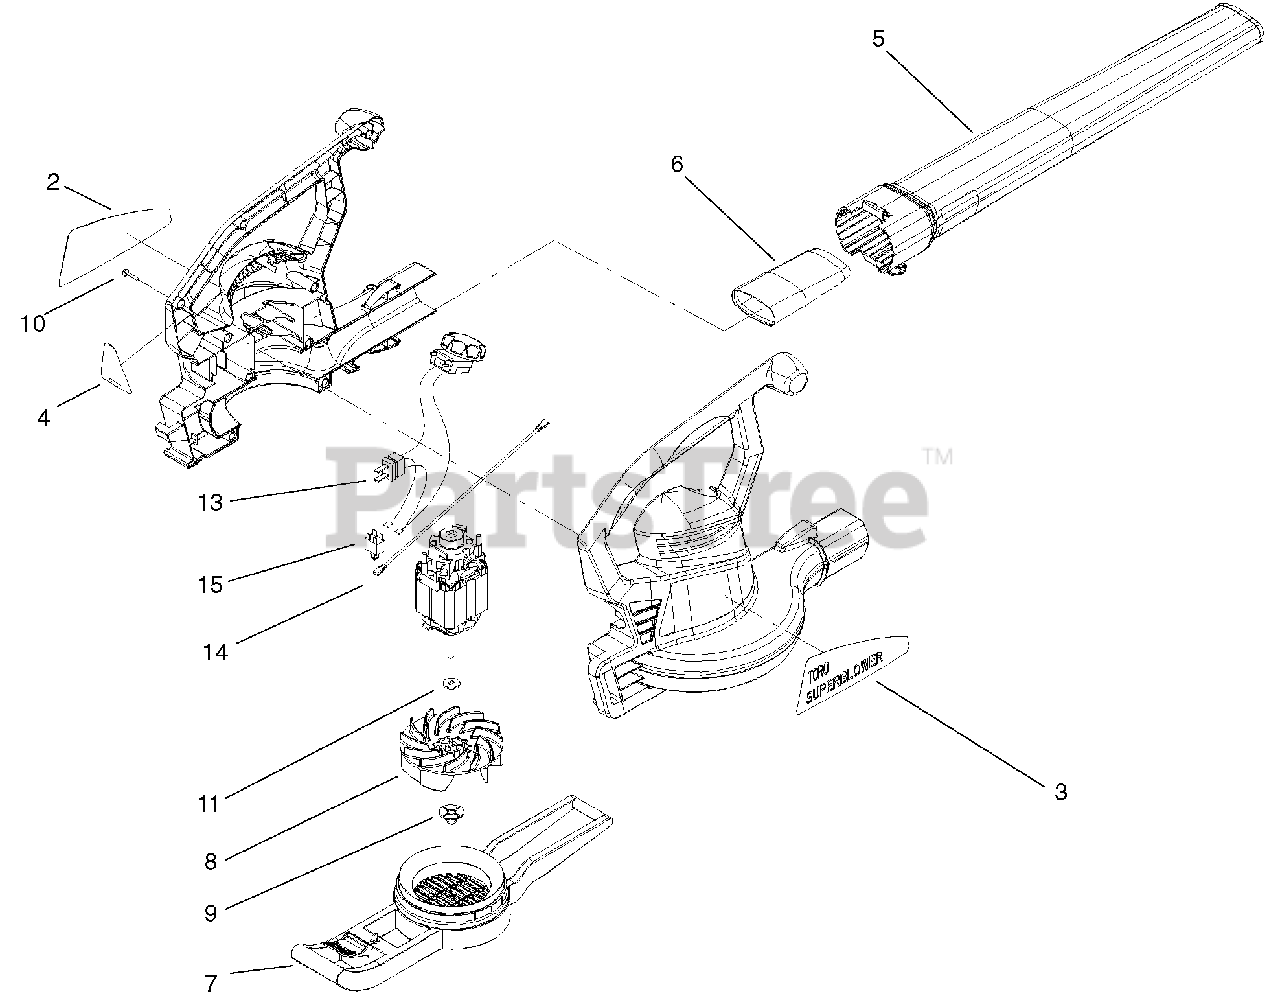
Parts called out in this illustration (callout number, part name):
2	Decal-Serial, Superblower
2:1	Label Stock-Serial
3	DECAL-SUPERBLOWER
4	DECAL-LOCK, CORD
5	TUBE-BLOWER
6	TUBE-INSERT
7	COVER-INLET
8	IMPELLER-BLOWER
9	NUT-IMPELLER
10	SCREW-PPH
13	WIRE HARNESS ASM, 2 SPEED
14	WIRE-JUMPER
15	SWITCH-INTERLOCK
